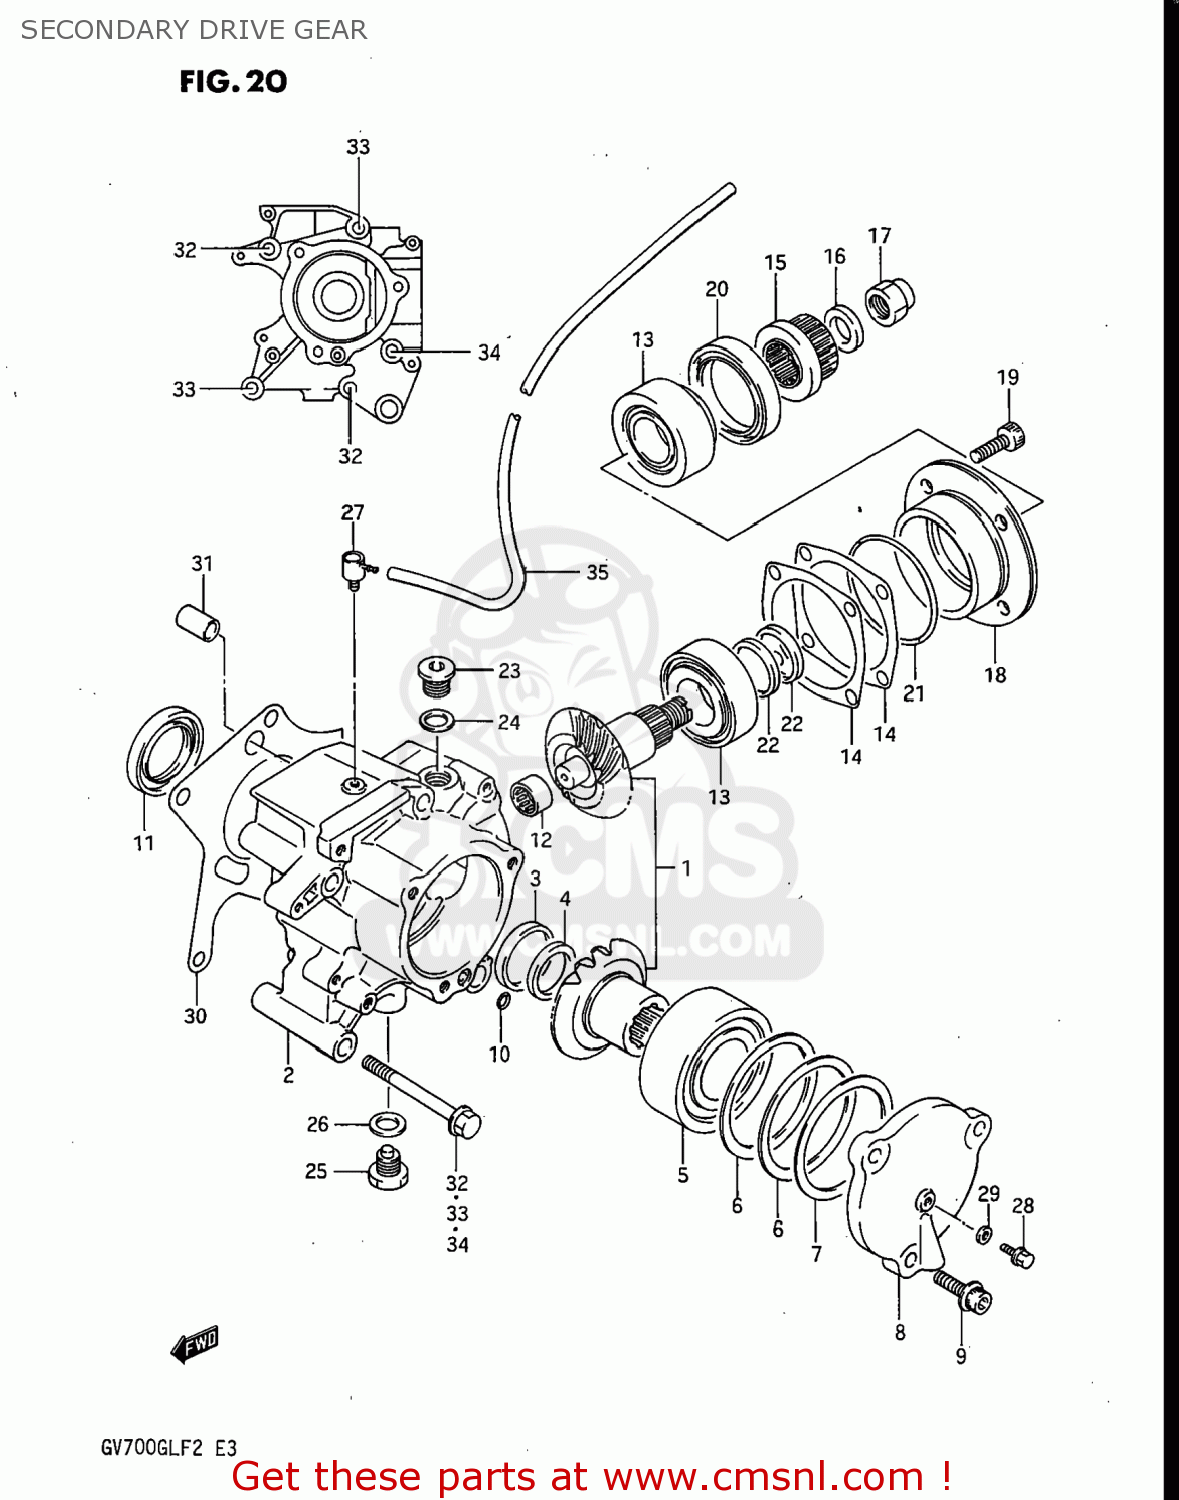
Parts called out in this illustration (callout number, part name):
1	GEAR,SECONDARY DRIVEN BEVEL
2	CASE,SECONDARY GEAR
3	HOUSING,SECONDARY DRIVE SHIM
4	SHIM,SECONDARY DRIVE
5	BALL BEARING 35X72X27
6	SHIM,SECONDARY DRIVE
7	O-RING (D:1.9 ID:69)
8	HOUSING,SECONDARY DRIVE BEARING
9	BOLT
10	O RING(D:1.9,ID:5.7)
11	SEAL,OIL(35X52X6)
12	BEARING(16X24X12)
13	TAPER,ROLLER BEARING
14	SHIM
15	COUPLING,SECONDARY DRIVE
16	WASHER(16X29X4)
17	NUT
18	HOUSING,SECONDARY DRIVEN BEVEL
19	BOLT
20	SEAL,OIL(48X64X6)
21	O RING(D:2.1,ID:66.2)
22	SHIM,SECONDARY DRIVEN HOUSING
23	PLUG
24	GASKET(14X19.2X2) (NAS)
25	PLUG
26	GASKET(14X19.2X2) (NAS)
27	BPLUG,BEVEL GEAR BREATHER
28	BOLT
29	GASKET(5.3X9.3X1.2) (NAS)
30	GASKET,SECONDARY GEAR CASE (MCA)
31	PIN(10.4X13X22)
32	BOLT, FRONT
33	BOLT 8X85
34	BOLT (8X95)
35	HOSE
